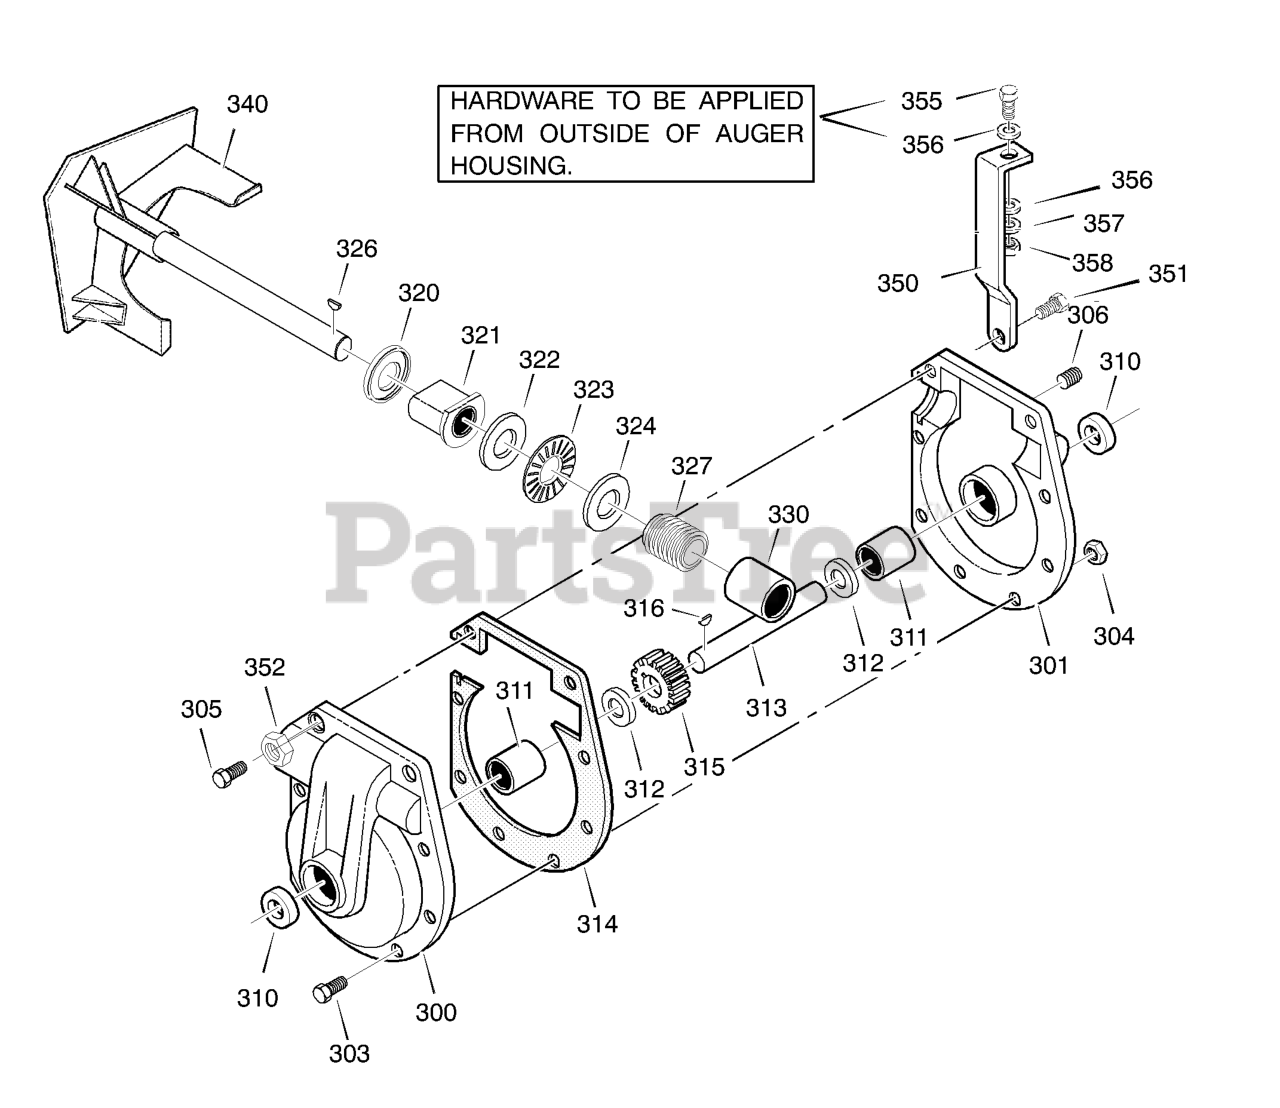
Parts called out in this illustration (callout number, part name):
300	CASE, GEAR, RH
301	CASE, GEAR, LH
303	SCREW, 5/16-24 x 1.00
304	NUT, 5/16-24
305	SCREW, 5/16-24 x 1.75
306	PLUG, PIPE 0.25-18
310	SEAL, OIL
311	BEARING, SLEEVE
312	WASHER, FLAT
313	SHAFT, AUGER OUTPUT
314	GASKET, GEAR BOX
315	WORM GEAR
316	KEY, WOODRUFF #91
320	RING, QUAD 0.924 ID
321	BEARING, FLANGE
322	WASHER, FLAT
323	BEARING, ROLLER
324	WASHER, FLAT
330	BEARING, SLEEVE
350	BRACE, GEAR BOX
352	NUT, 5/16-24
355	SCREW 5/16-18 x1.25
356	WASHER
357	WASHER
358	NUT, 5/16-18
